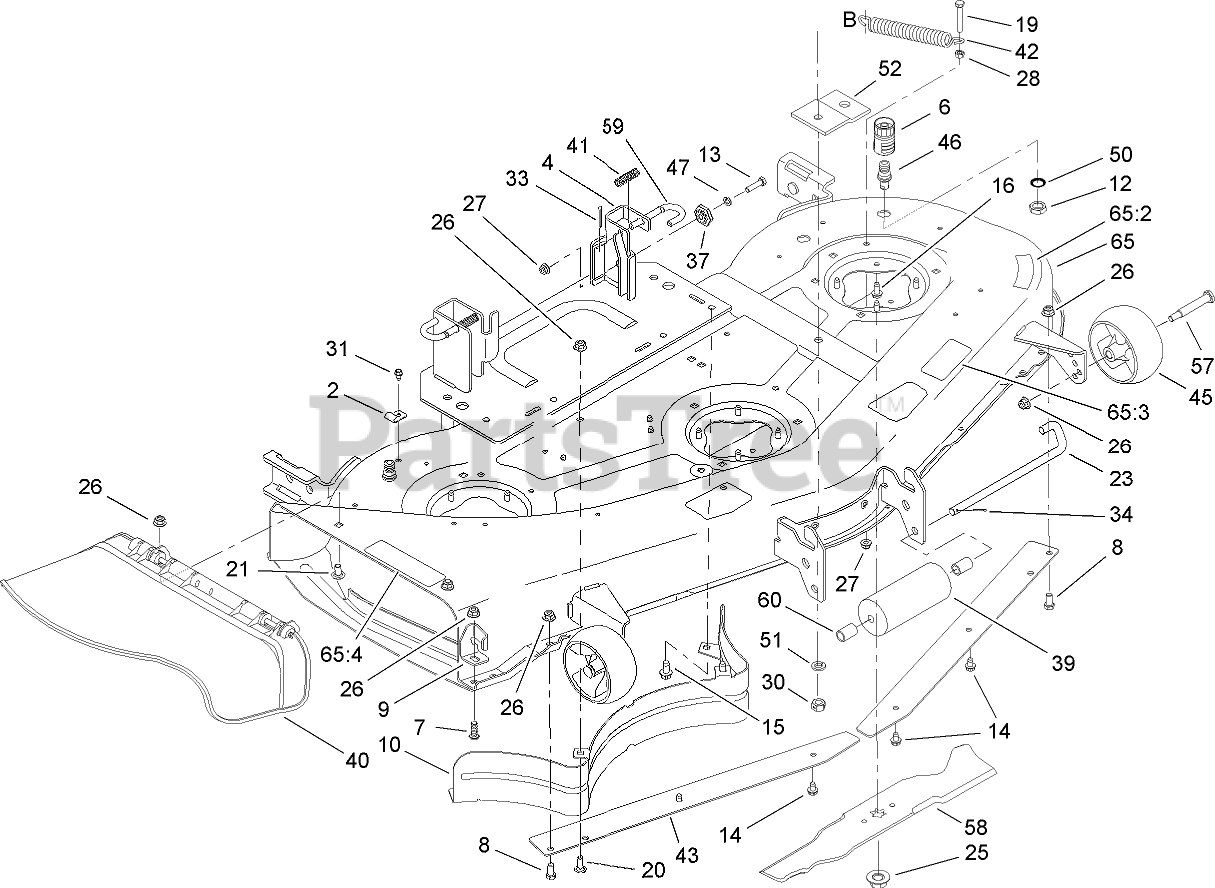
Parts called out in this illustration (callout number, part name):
2	BRACKET-RETAIN, HOOK
4	LH HANGER BRACKET ASM
6	ADAPTER-NOZZLE, WATER
7	SCREW-HH
8	SCREW-HH
9	STOP-CHUTE
10	BAFFLE
12	NUT-HEX
13	SCREW-HH
14	SCREW-TAP
15	SCREW-HWHTF
16	SCREW-HH
19	SCREW-HH
20	BOLT-CARR
21	BOLT-CARR
23	PIN-ROLLER
25	NUT-LOCK, FLANGE
26	NUT-LOCK, FLANGE
27	NUT-LOCK, FLANGE
28	NUT-HEX
30	NUT-HEX, LOCK
31	NUT-LOCK, FLANGE
33	PIN-COTTER
34	PIN-COTTER
37	GEAR-ADJUSTMENT, DECK
39	ROLLER
40	CHUTE DEFLECTOR ASM
41	SPRING-COMPRESSION
42	SPRING
43	SKIRT-DECK
45	WHEEL-DECK, FRONT
46	NOZZLE-WATER, DECK
47	WASHER-LOCK
50	WASHER-LOCK
51	WASHER-LOCK
52	BRACKET-STABILIZER
57	BOLT-SHOULDER
58	BLADE-18.50
59	PIN-HANDLE, DECK RELEASE
60	SPACER
65	DECK AND DECAL ASM
65:2	DECAL-DANGER, DECK
65:3	DECAL-BELT ROUTING, DECK
65:4	DECAL-DANGER
